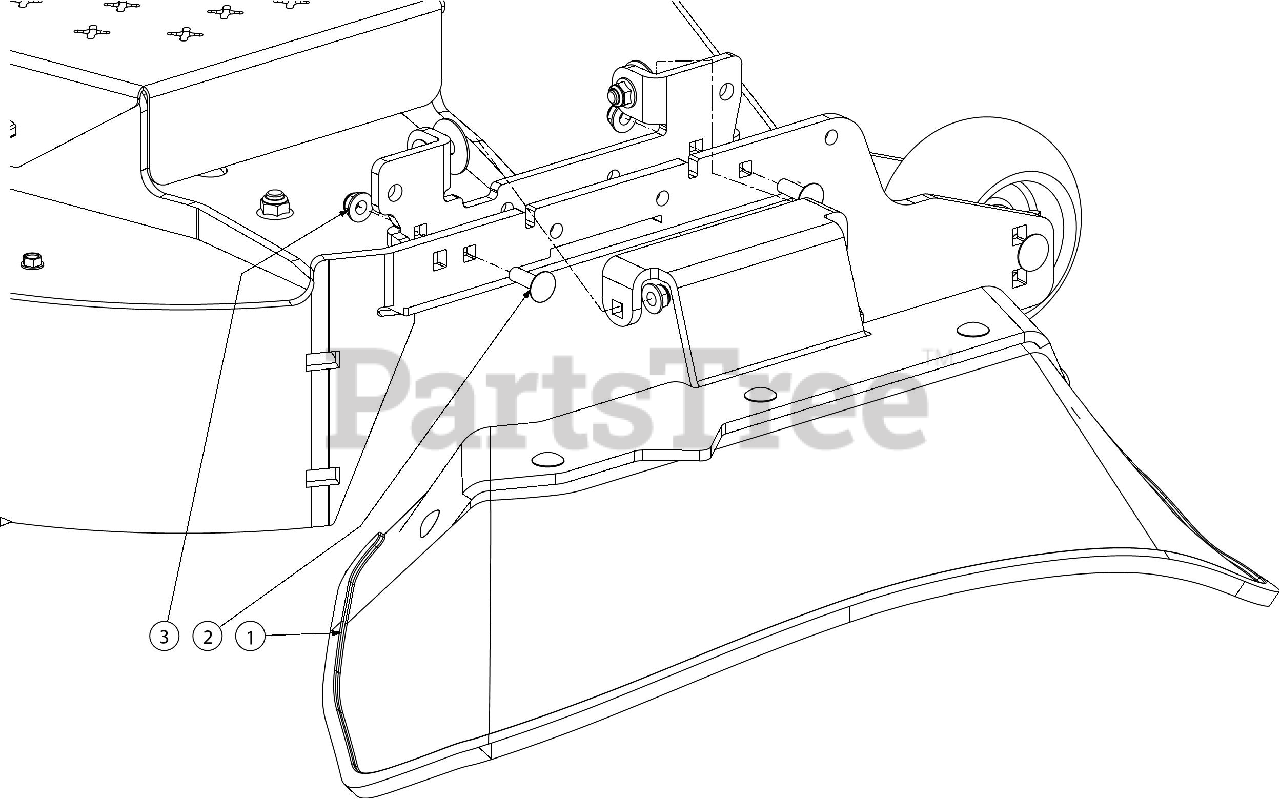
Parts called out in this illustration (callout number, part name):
1	DECK CHUTE ASSEMBLY
2	CARRIAGE BOLT 5/16-18 x 1.00
3	FLANGE LOCK NUT 5/16-18
